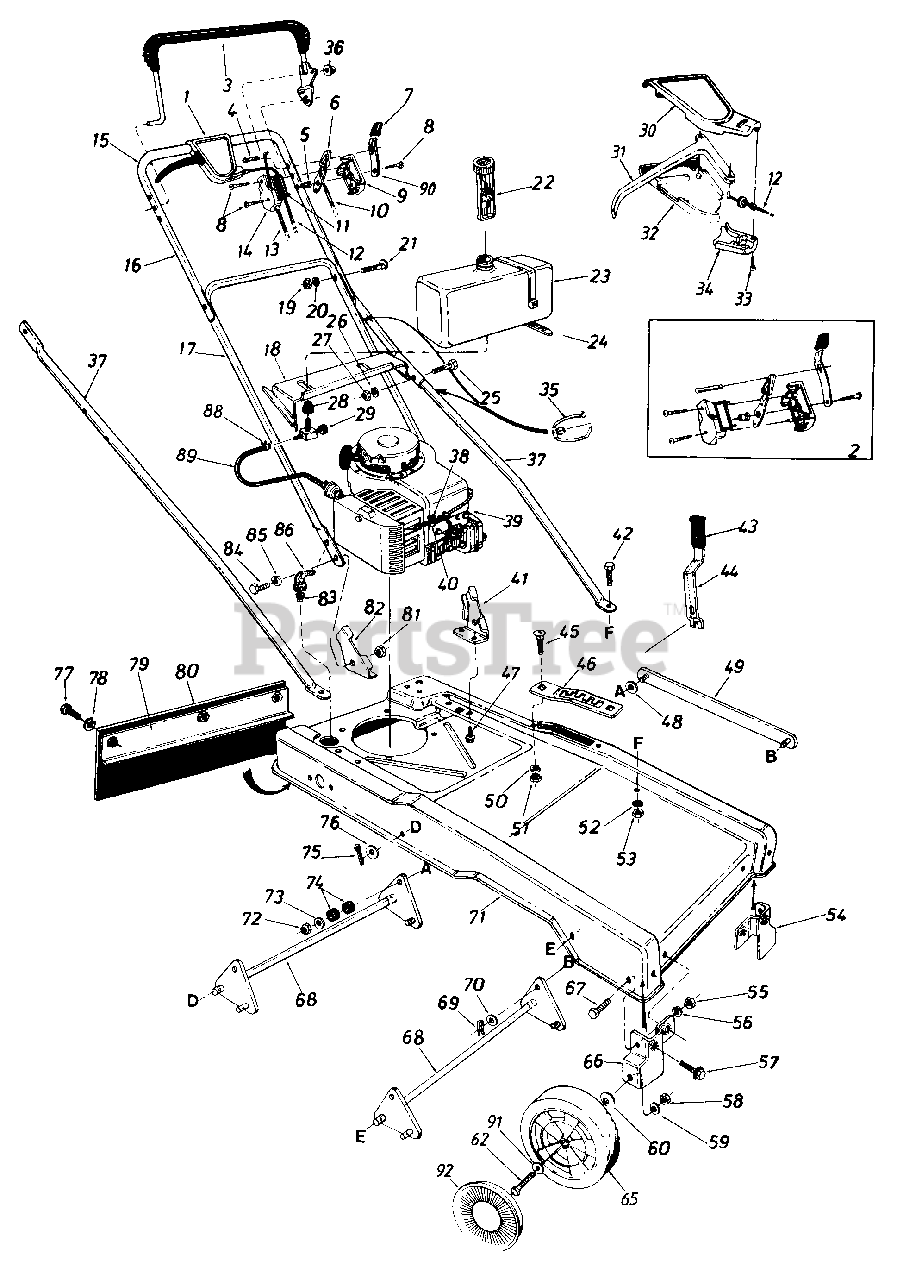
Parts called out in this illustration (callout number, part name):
2	Control Housing Comp.
3	Control Handle Ass'y.
4	Lock Pin
5	Control Disc Pin
6	Throttle Control Lever
7	Spring Lever Knob
8	Truss Mach. Hi-B Tap Scr. #12 x 1.50" Lg.
9	Control Panel Half
10	Throttle Control Wire 43" Lg.
11	Control Label-Throttle
12	Self-Propelled Cable 44" Lg.
13	Drive Clutch Cable-46" Lg.
14	Clutch Panel Half
16	Upper Handle
17	Lower Handle
18	Gas Tank Mounting Brkt.
19	Hex Nut 5/16-18 Thd.
20	L-Wash. 5/16" I.D.
21	Carriage Bolt 5/16-18 x 1.50" Lg.*
22	Gas Gauge 1-3/4-6 x 5.50" Lg.
23	Gas Tank
24	Cable Tie 30.6" Lg.
25	Hex Bolt 5/16-24 x 1.25" Lg.
26	L-Wash. 5/16" I.D.
27	Hex Nut 5/16-24 Thd.
28	Bushing-Gas Tank
29	Fuel Shut-Off Valve w/Screen
30	Control Cover Half-Upper
31	Control Lever
32	Control Cover Half-Lower
33	Flat "C" Sunk Hd. Tap Scr. #10 x .75" Lg.
34	Cable Mounting Cap
35	Cable Tie
36	Push Cap
37	Strut .75" O.D. x 43.44" Lg.
38	Hex Sems Scr. #10-32 x .62" Lg.
39	Engine-5 H.P.
40	Casing Clamp
41	Handle Mount Brkt.-L.H.
42	Hex Bolt 5/16-18 x .75" Lg.
43	Grip-Black
44	Lift Handle
45	Carriage Bolt 5/16-18 x .62" Lg.
46	Lift Handle Support Brkt.
47	Hex Wash. Hd. B-Tap Scr. 5/1 6-1 8 x .50
48	Fl-Wash. .406" I.D. x 1.25" O.D.
49	Connecting Link Ass'y.
50	L-Wash. 5/16" I.D.*
51	Hex Nut 5/16-18 Thd.*
52	L-Wash. 5/16" I.D.*
53	Hex Nut 5/16-18 Thd.*
54	Wheel Brkt. Ass'y.-L.H.
55	Hex Nut 5/16-18 Thd.*
56	L-Wash. 5/16" I.D.*
57	Hex Sems Bolt 5/16-18 x .75" Lg.
58	Hex Cent. L-Nut 3/8-16 Thd.
59	L-Wash. 3/8" I.D.*
60	Bell-Wash. .400" I.D. x .88" O.D.
62	Front Axle Bolt
65	Wheel Ass'y. Comp. 8" x 2"
66	Wheel Brkt. Ass'y.-R.H.
67	Hex Sems Bolt 5/16-18 x .75" Lg.
68	Lift Brkt. Shaft Ass'y.
69	Intern. Cotter Pin 5/16" Dia.
70	Fl-Wash. 885" I.D. x .88"
71	Hi-Wheel Frame
72	Hex Ins. L-Nut 3/8-24 Thd.
73	Fl-Wash. .385" I.D. x .88"
74	Rubber Wash. .33" I.D. x .87" O.D.
75	Cotter Pin 1/8" Dia. x 1" Lg. *
76	Fl-Wash. .51" I.D. x 1.0"
77	Hex Bolt 1/4-20 x .62n Lg.*
78	L-Wash. 1/4" I.D.*
79	Retaining Strip Ass'y. 3" x 15" Lg.
80	Rear Flap 7.5 x 20" Lg.
81	Hex Nut 3/8-16 Thd.*
82	Handle Mount Brkt.-R.H.
83	Part of Engine
84	Hex Bolt 3/8-16 x 75n Lg.*
85	L-Wash. 3/8" I.D.*
86	90 Deg. Elbow Male to Female 3/8
88	Hose Clamp-.406" Dia.
89	Fuel Line 15" Lg.
90	Lockout Lever
91	Wave Wash..53" I.D. x 78" O.D.
92	Hub Cap
